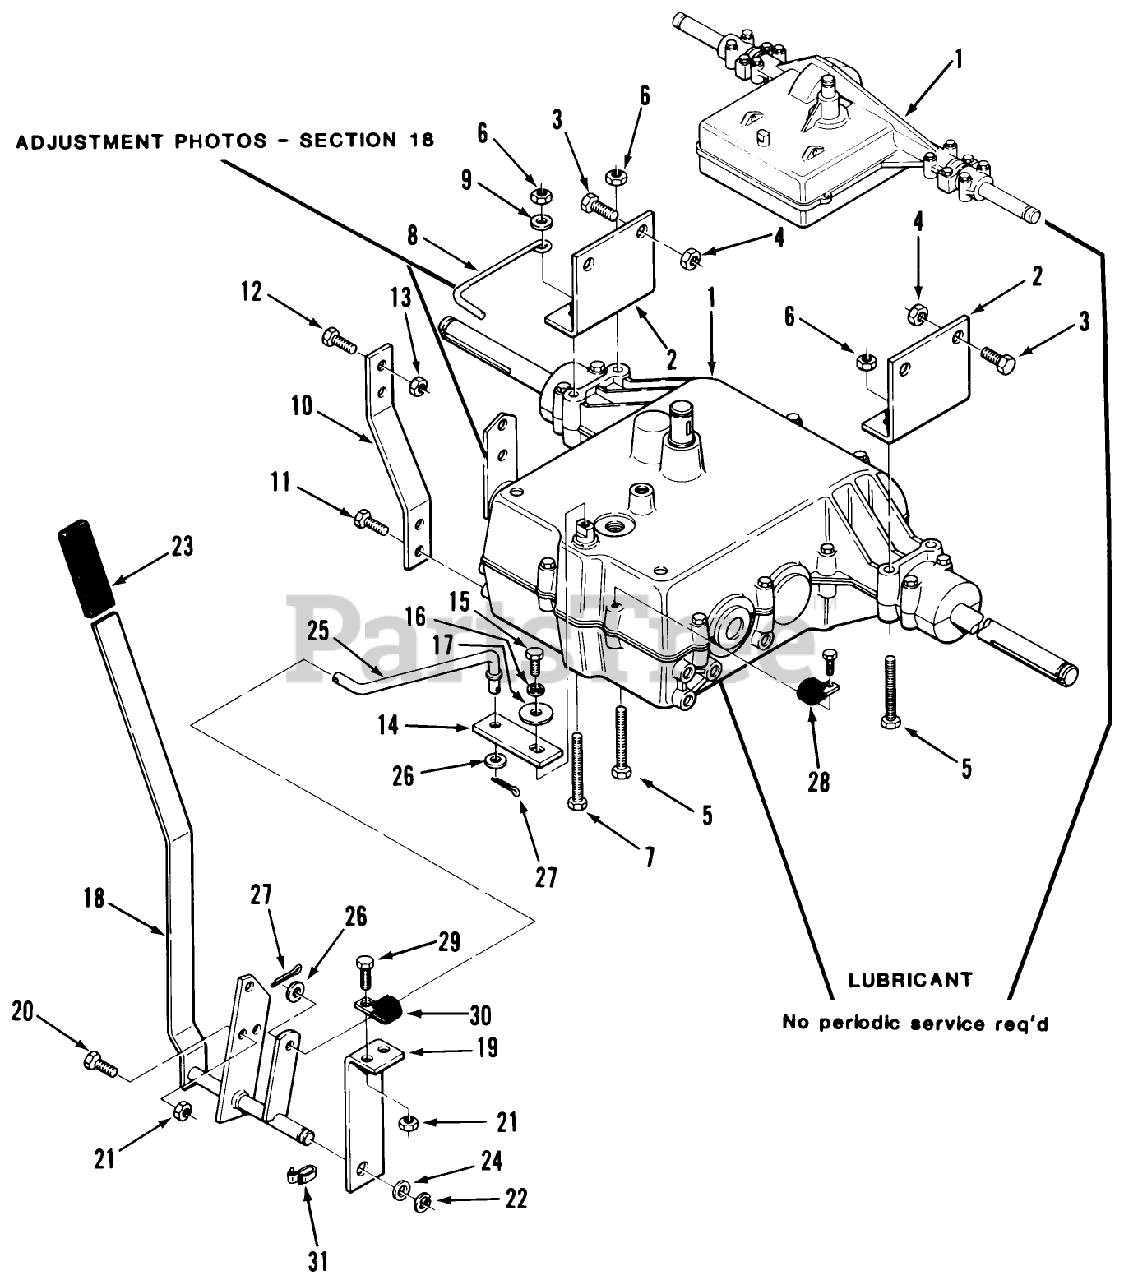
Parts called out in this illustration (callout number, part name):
1	Peerless Transmission (900-012A) 108-3 Only
1	Transmission Peerless Model 829
8	STOP BRAKE
9	WASHER 5/16 SAE
10	TORQUE STRAP *R
11	Screw
17	WASHER
18	ASSY LEVER SHIFT *R
24	Washer
26	WASHER 5/16 SAE
28	J-CLIP
30	J-CLIP
31	CLIP-CABLE
